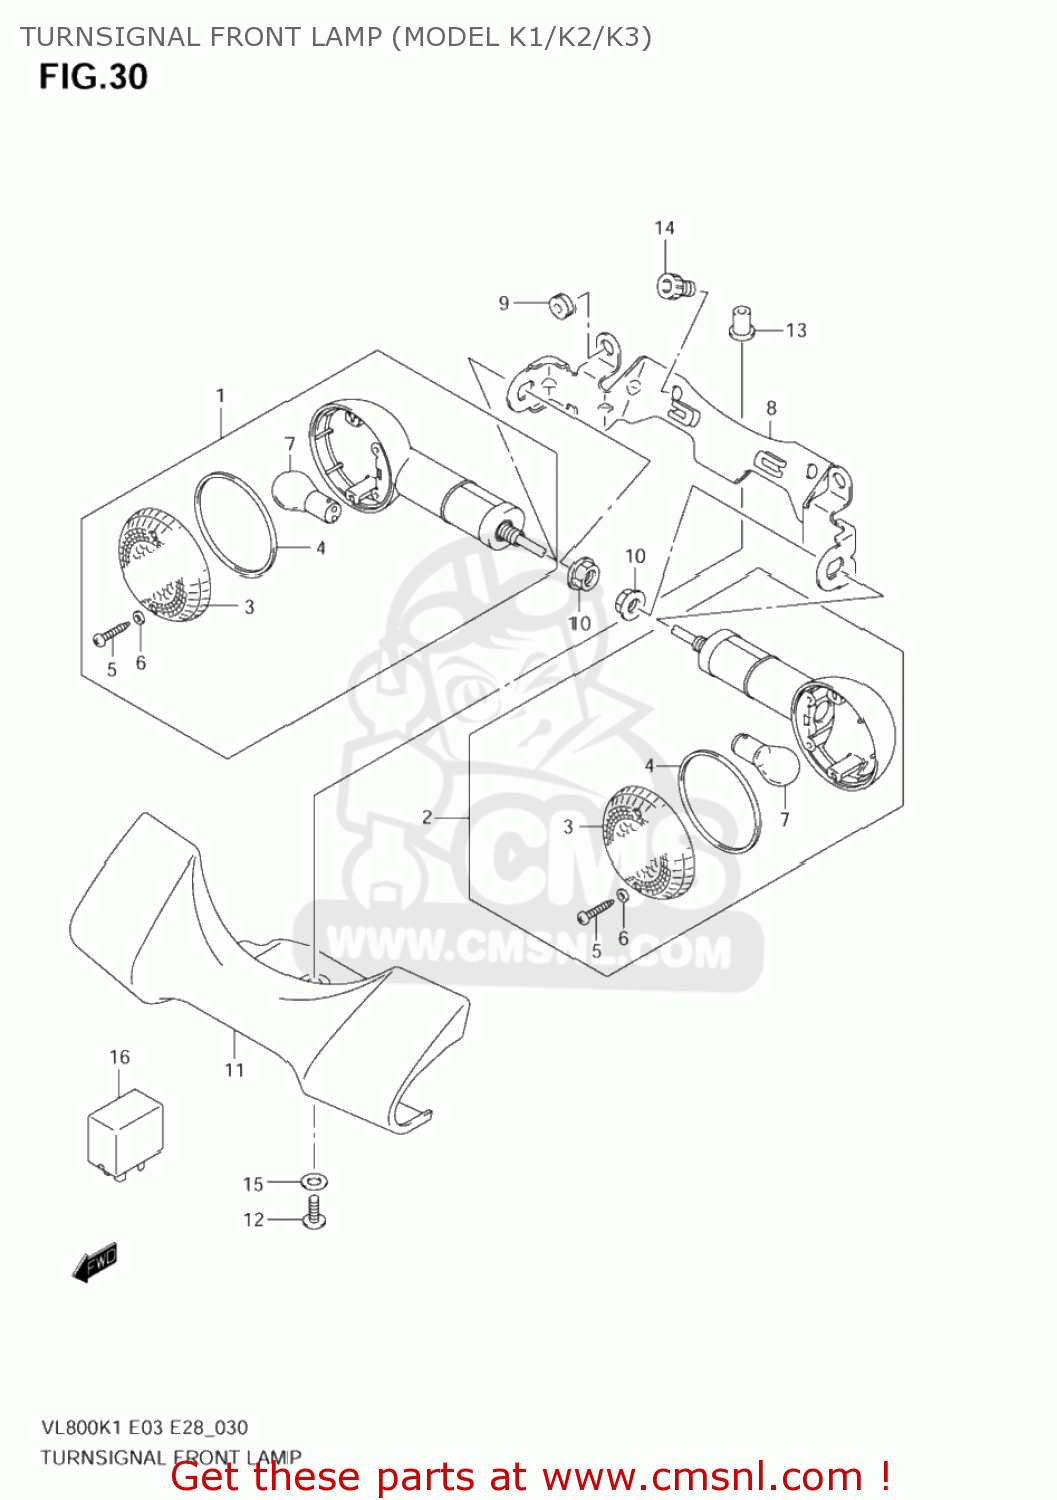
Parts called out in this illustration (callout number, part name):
1	LAMP ASSY,FR TURN SIGNAL,R
2	LAMP ASSY,FR TURN SIGNAL,L
3	LENS
4	GASKET (NAS)
5	SCREW
6	GASKET (NAS)
7	BULB(12V21/5W)
8	BRACKET
9	CUSHION
10	NUT
11	COVER,FRONT TU
12	SCREW(5X16)
13	NUT
14	PLUG
15	WASHER(5.5X14X1.2)
16	RELAY ASSY,TURNSIGNAL LAMP
